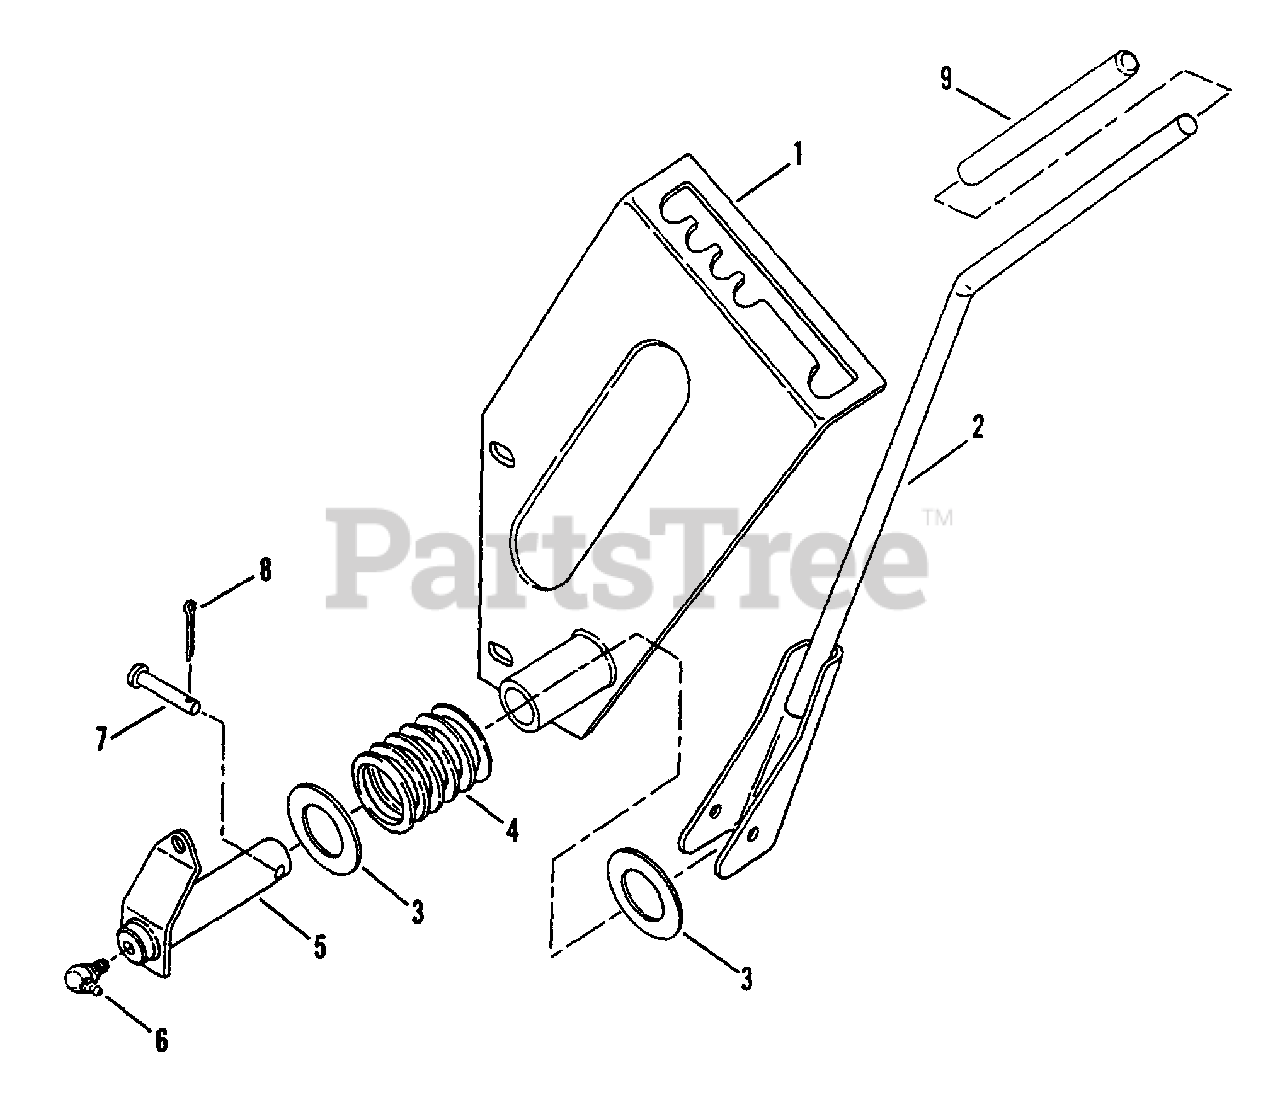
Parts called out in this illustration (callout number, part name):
1	SHIFT QUADRANT, Structure
2	HANDLE, Shift
3	WASHER, Thrust 1.62x.775x.025
4	SPRING, Tension
5	ARM, Structure
6	LUBE FITTING, 90 Deg. 1/4-28
7	CLEVIS PIN, 1/4X1-1/4
8	COTTER-PIN, 3/32 x 3/4"
9	GRIP, Shift Handle
